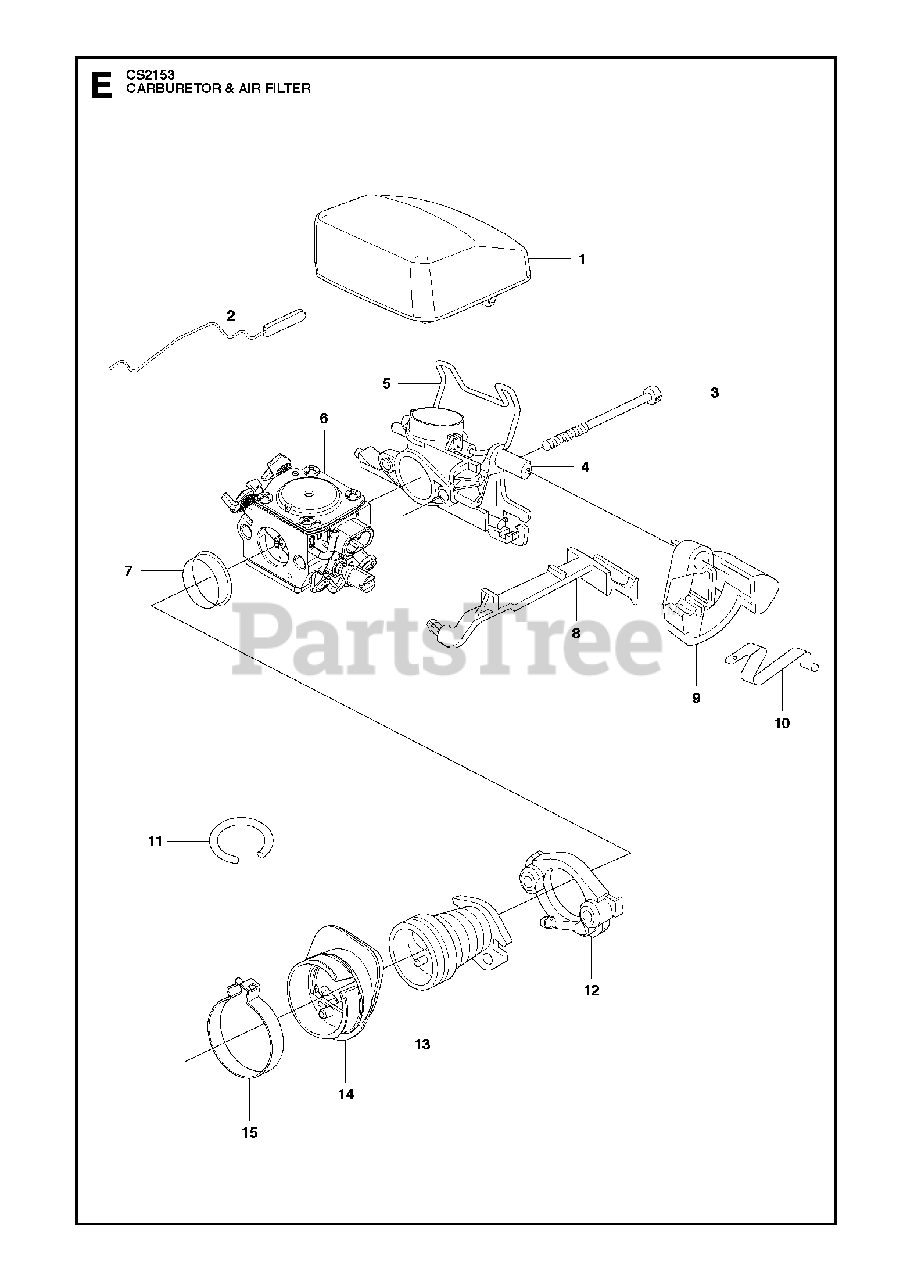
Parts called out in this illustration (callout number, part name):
1	AIR FILTER - NYLON (B)
1	AIR FILTER - NYLON (Y)
1	AIR FILTER - FELT
2	THROTTLE ROD
4	INLET ELBOW
5	FILTER CLAMP
8	CHOKE CONTROL
11	HOSE, IMPULSE
14	PARTITION
15	CLAMP, INTAKE
